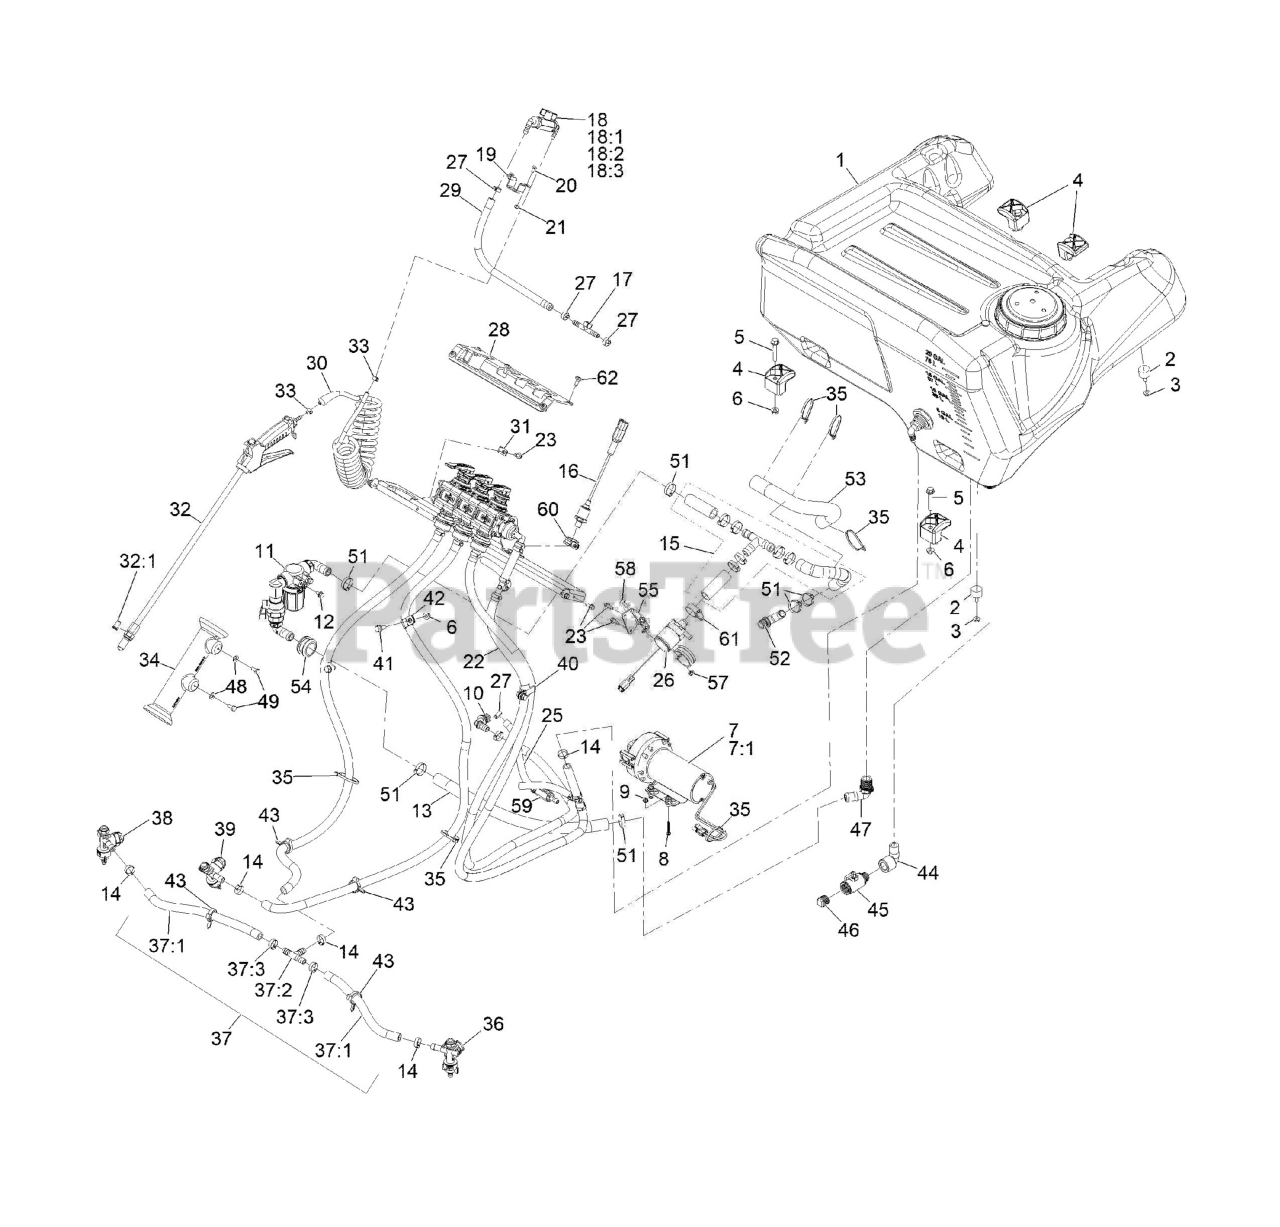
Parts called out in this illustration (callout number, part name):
1	Tank-Sprayer
5	SCREW-HHF
7	Pump-Diaphragm, 3.8 GPM
7:1	KIT-DIAPHRAM PUMP
8	SCREW-SHWH
10	FITTING-ELBOW, BARBED
11	STRAINER ASM
12	SCREW-HHF
13	HOSE-WATER
14	CLAMP OETIKER 0.716"" CLOSED 0.826"" OPEN
15	ASM-, 3/4 Pvc Reinforced Water Hose
16	TRANSDUCER-PRESSURE
17	FITTING-TEE
18	Wand Control ASM
18:1	VALVE-BALL
18:2	FITTING-ELBOW-90
18:3	FITTING-ELBOW-90
19	BRACKET-VALVE
20	BOLT-CARR
21	NUT-LOCK, NI
22	Manifold-Valve, Control ASM
23	SCREW-HWH
25	Hose-Water
26	Pump-Centrifugal
28	Cover-Controls
29	HOSE-WATER, 3/8 PVC RED
30	Hose-Coiled, 04X15Ft
31	CLAMP-R
32	SPRAY WAND ASM
32:1	STRAINER-NOZZLE, 50M 5PSI
34	HOLDER-WAND
35	TIE-CABLE
36	LEFT NOZZLE SUB ASM
37	HOSE ASM
37:1	HOSE-WATER
37:2	FITTING-TEE
37:3	CLAMP OETIKER 0.716"" CLOSED 0.826"" OPEN
38	RIGHT NOZZLE SUB ASM
39	CENTER NOZZLE SUB ASM
41	SCREW-HHF
42	CLIP-LOOM
43	CLAMP-HOSE
44	ELBOW-90 DEG
45	MICROVALVE
47	ELBOW-HOSEBARB
48	WASHER-FLAT
49	SCREW-HH
52	FITTING-ELBOW
53	SLEEVE-CORRUGATED, SPLIT
54	GROMMET
55	Brkt-Recir Pump
58	SCREW-CARR
59	Valve-3/8 Check
60	R-Clamp
61	CLAMP-HOSE
62	SCREW-SHOULDER
